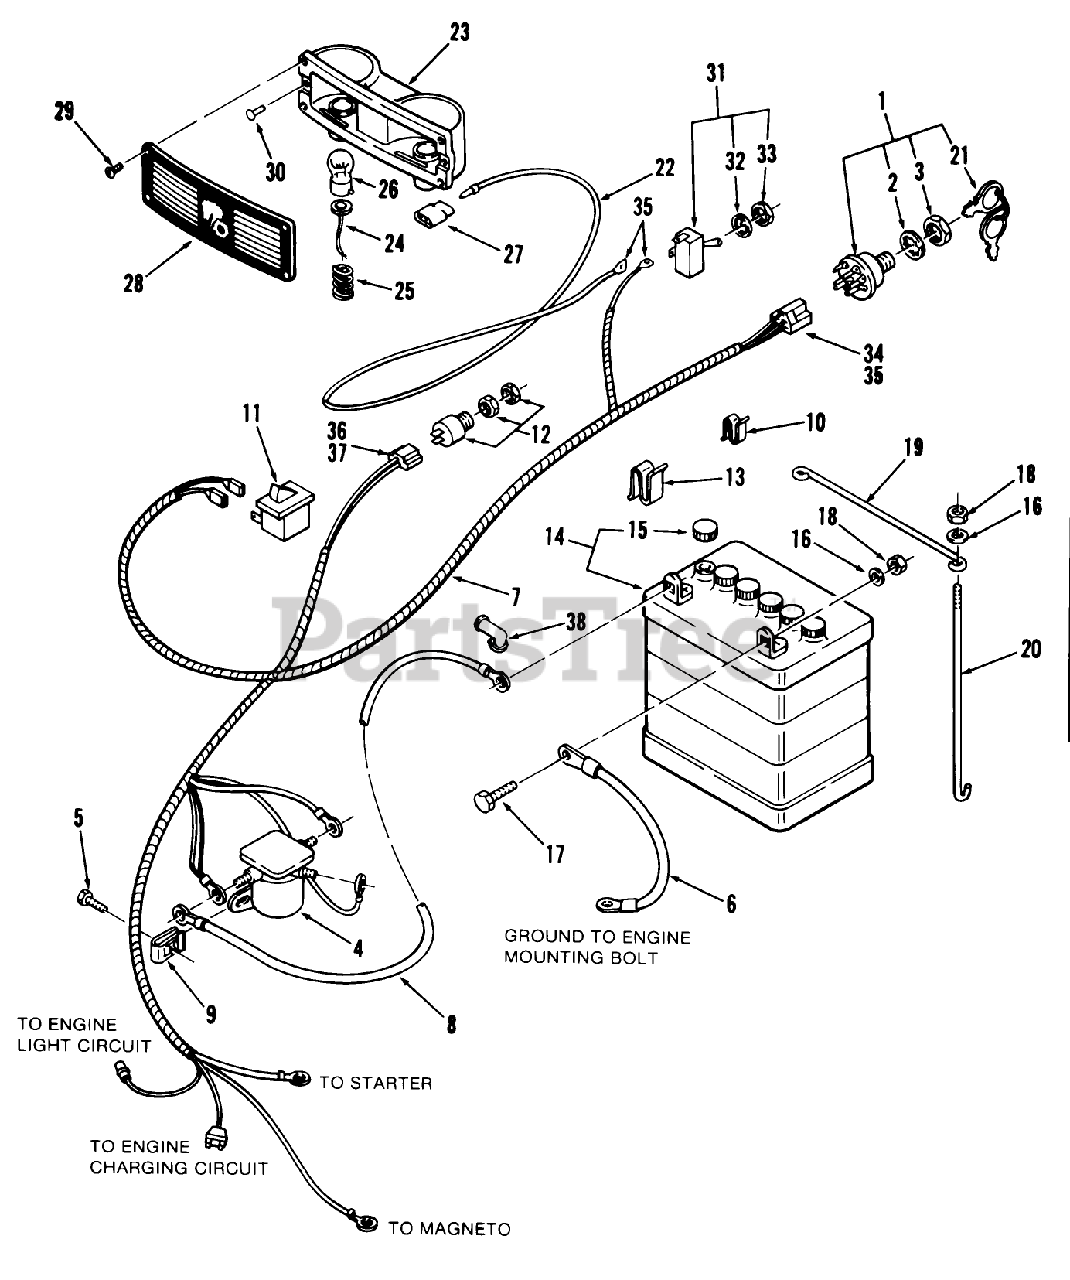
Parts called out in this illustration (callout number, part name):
1	ASSY-SWITCH IGNITION
5	HEX WASHER HD SCREW
12	SWITCH
19	ROD-HOLD DOWN
25	SPRING
26	BULB
31	SWITCH-LIGHTS
32	TAB-WASHER
33	NUT-HEX
36	Connector Body
